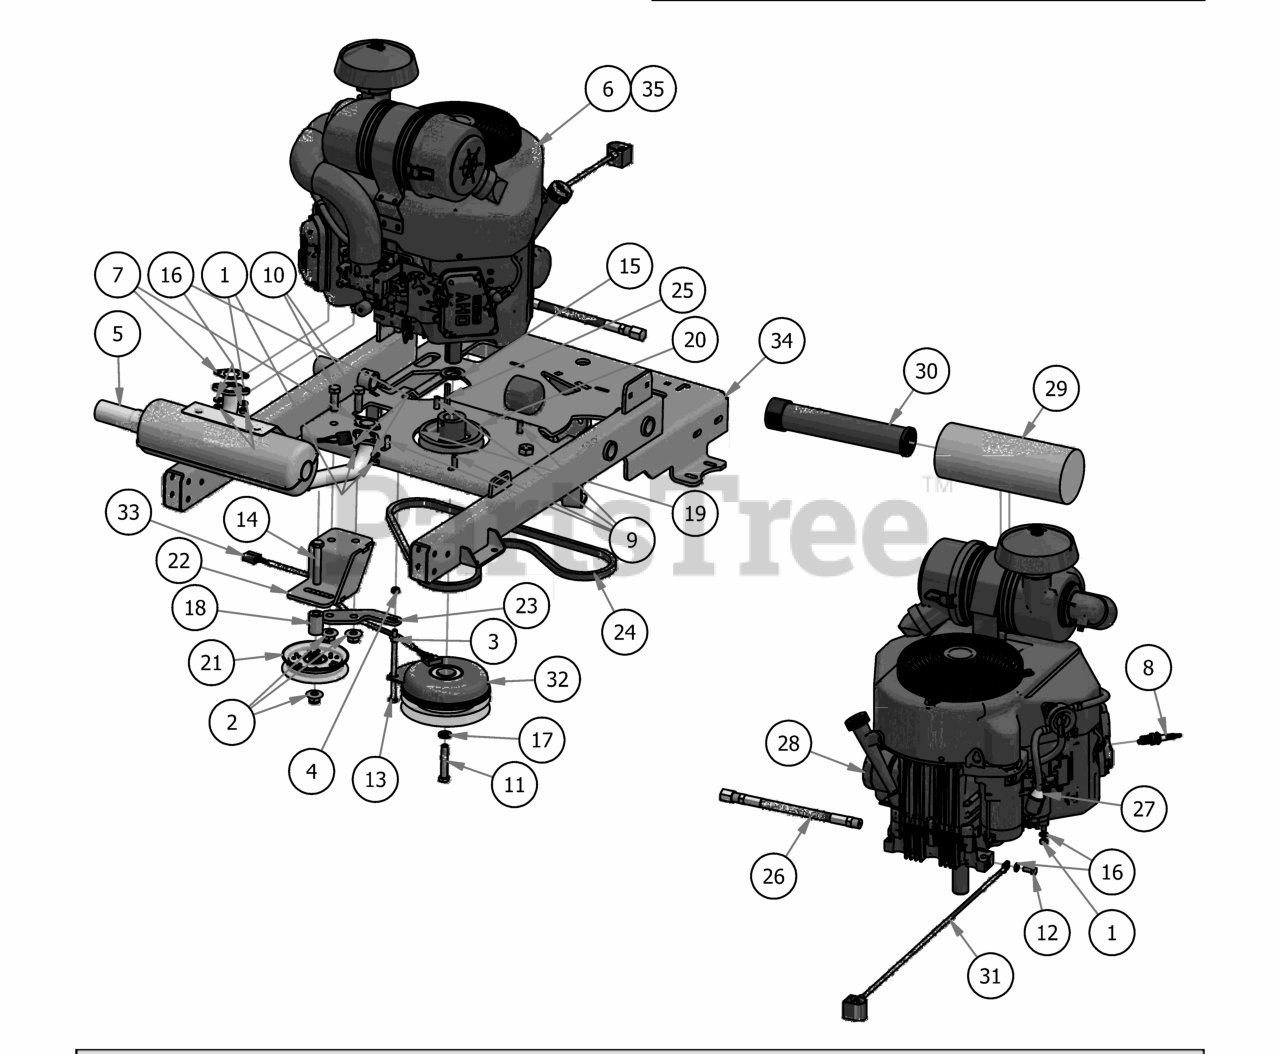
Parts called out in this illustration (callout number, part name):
1	M8-1.25 Zinc Nut
2	1/2-13 Nylon Flange Nut
3	5/16" Flange Nut
4	5/16-18 Nylock Jam Nut 1/2 Nut
5	Exhaust-Stand On-FX691V Kawasaki
7	Exhaust Gasket
8	Spark Plug - Kawasaki
9	3/8 x 1 1/8 bolt
10	1/2" x 1 1/2" Hex Bolt
11	7/16" x 2 1/2" Hex Bolt
12	M8x1.20x20MM Hex head bolt
13	5/16-18 x 5-1/2 GR 5 Hex Bolt
14	1/2-13 x GR 5 Hex Bolt Zinc
15	1 1/8" Flat Spacer
16	5/16" Lock Washer
17	7/16" Lock Washer
18	.502 ID X .750 OD X 1.500 Long Spacer
19	5/16 Set Screw
20	4 3/4 Motor Pulley
21	4-3/4 Idler Pulley
22	Idler Pulley Bracket Weldment
23	2019 Stand On Clutch Stop Bracket
24	2019 Stand On Pump Belt (Timken# 47-2827)
25	1/4 x 2 Square key Stock
26	Oil drain Hose
27	Universal Inline Fuel Filter
28	Oil Filter
29	Canister Air Filter- Outer
30	Canister Air Filter- Inner
31	24" Black Ground Cable
32	Clutch Assembly
33	Clutch Pigtail
34	2019 Stand On Frame Weldment
35	Kawasaki Harness Adapter
